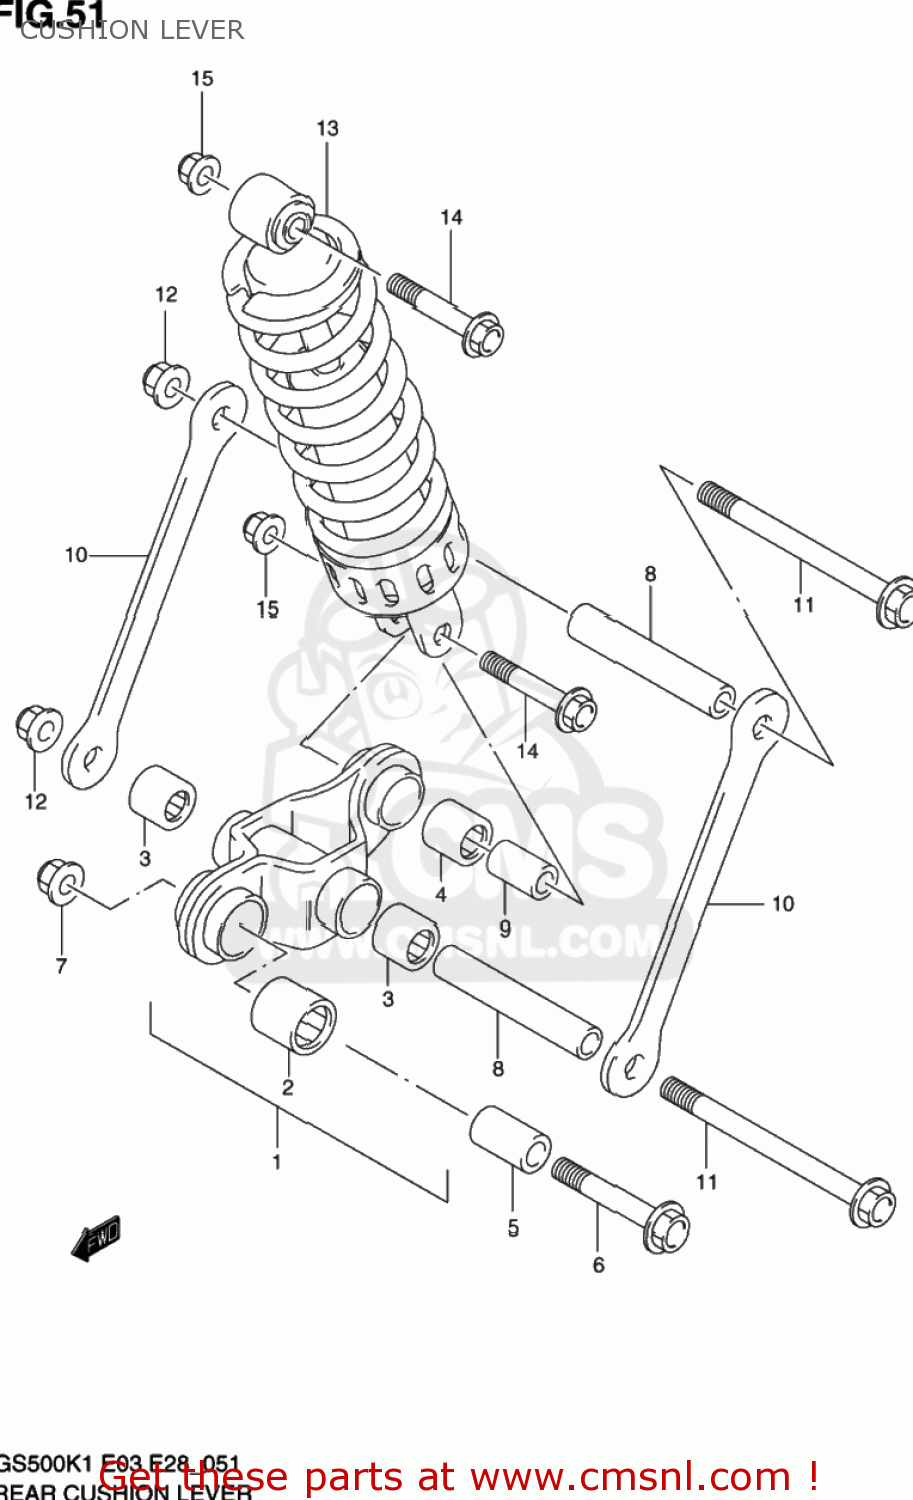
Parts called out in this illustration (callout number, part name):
1	LEVER SET,RR CUSHION
2	BEARING(20X27X26)
3	BEARING(17X24X25)
4	BEARING(17X24X26)
5	SPACER,RR CUSHION LEVER FR
6	BOLT(12X57)
7	NUT 12MM
8	SPACER(12X17X89)
9	SPACER,RR CUSHION LEVER
10	ROD,RR CUSHION LEVER
11	BOLT(12X118)
12	NUT 12MM
13	ABSORBER ASSY,
14	BOLT(10X52)
15	NUT
